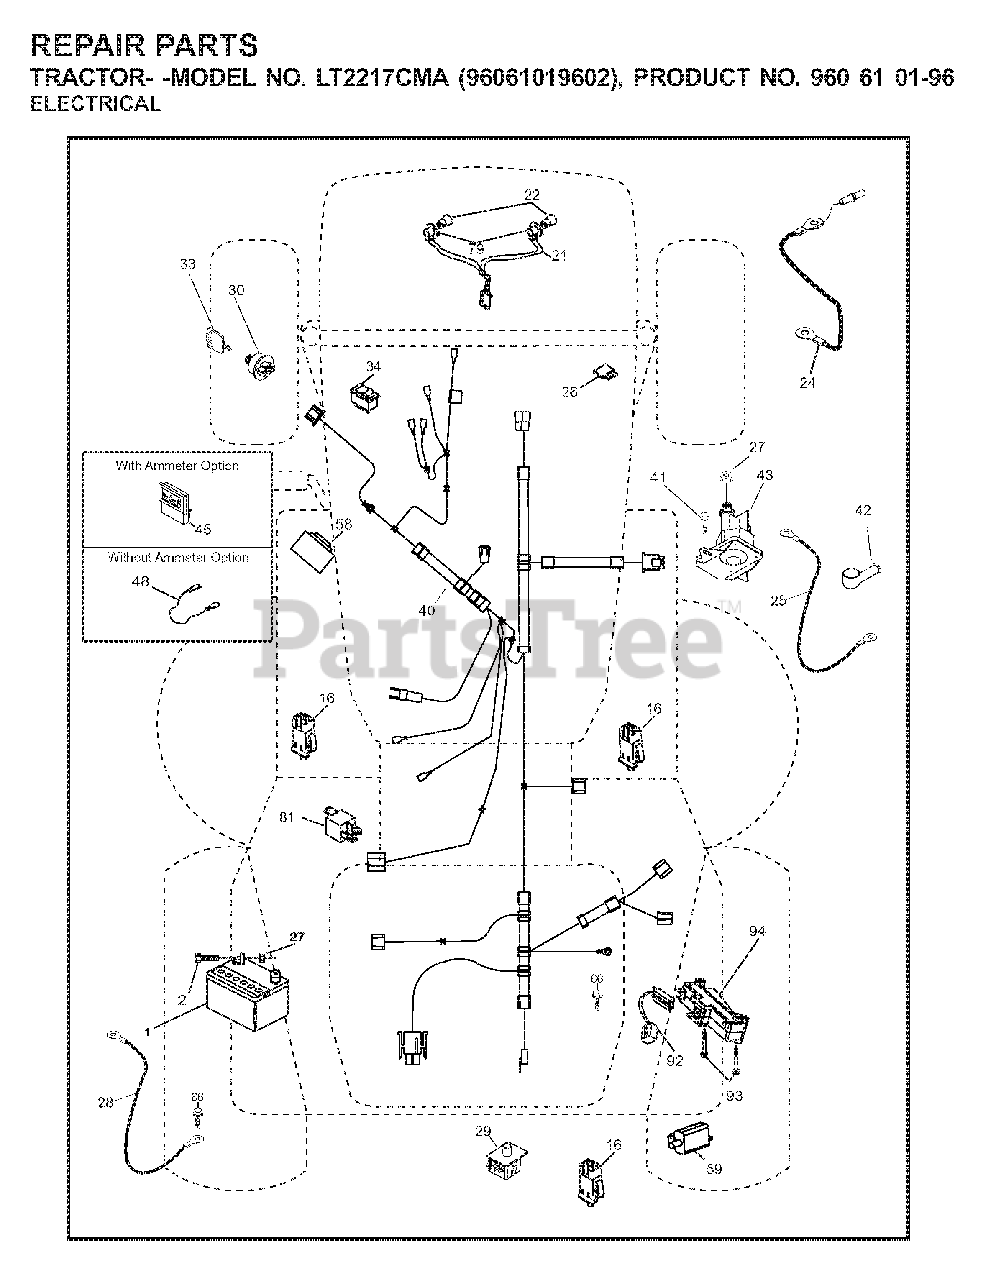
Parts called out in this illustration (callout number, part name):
1	REPL BY 532 12 38-99
16	SWITCH INTERLOOK PUSH-IN
21	HARNESS ASSY LIGHT
22	LIGHTBULB
24	BATTERY CABLE GT
25	CABLE BATTERY
26	FUSE 20AMP
27	NUT
28	CABLE GROUND
29	SWITCH.SEAT.DP W/RAMPS
30	SWITCH.IGN.DELTA.W.LGH.ROS
33	KEY.CHAIN.BLISTER.PACK.GEN.INT
34	SWITCH LT
42	TERMINAL COVER
43	SOLENOID.W/BRASS.PLUNG
58	BUZZER
66	SCREW LT
79	BULB HOLDER ASM.
81	RELAY.ASSY.T
92	HARNESS.PIGTAIL.CONSLE
93	SCREW.PLASTITE
94	MODULE.REVERSE.ROS
